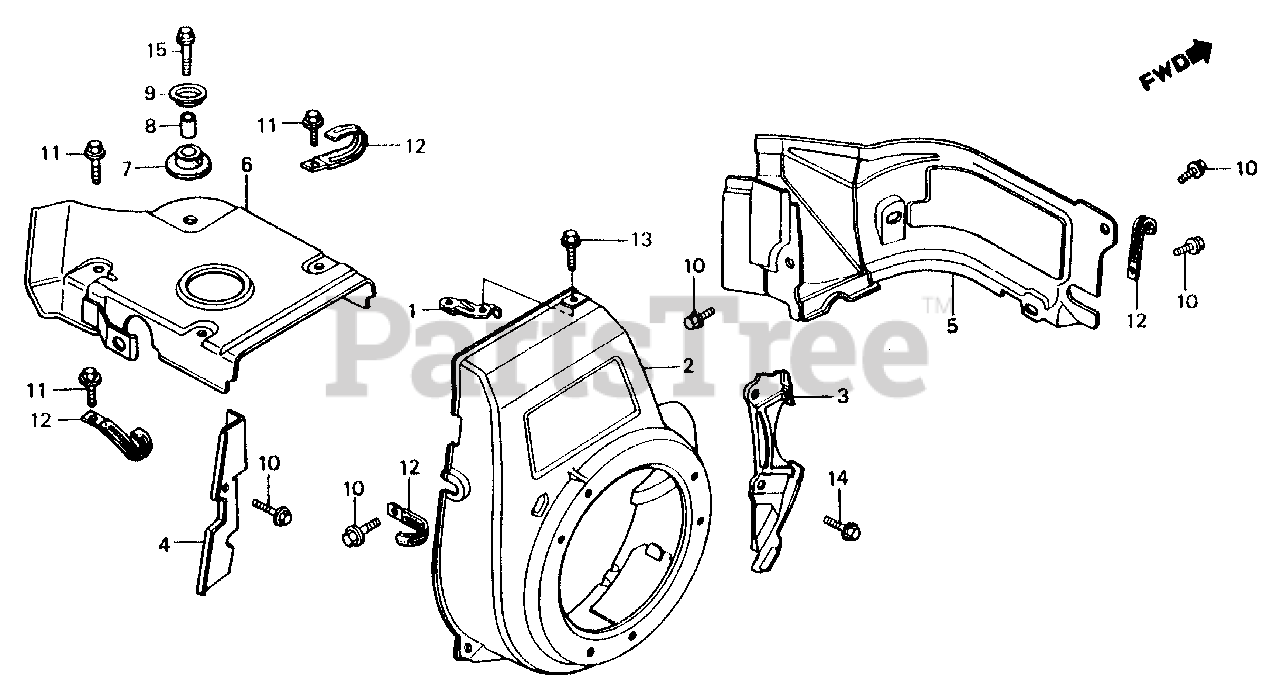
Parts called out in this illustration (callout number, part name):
1	STAY, FAN COVER
2	COVER ASSY., FAN *R8* (BRIGHT RED) (NOT AVAILABLE)
3	PLATE, SIDE
4	GUIDE, AIR
5	SHROUD *R8* (BRIGHT RED)
6	COVER, TOP *R8* (BRIGHT RED)
7	RUBBER, STOPPER
8	COLLAR, DISTANCE
9	PLATE, STOPPER
10	BOLT, FLANGE (6X12) (CT200)
11	BOLT, FLANGE (6X14)
12	CLIP (2X50)
13	BOLT, FLANGE (6X10)
14	BOLT, FLANGE (8X20)
15	BOLT, FLANGE (8X32)
